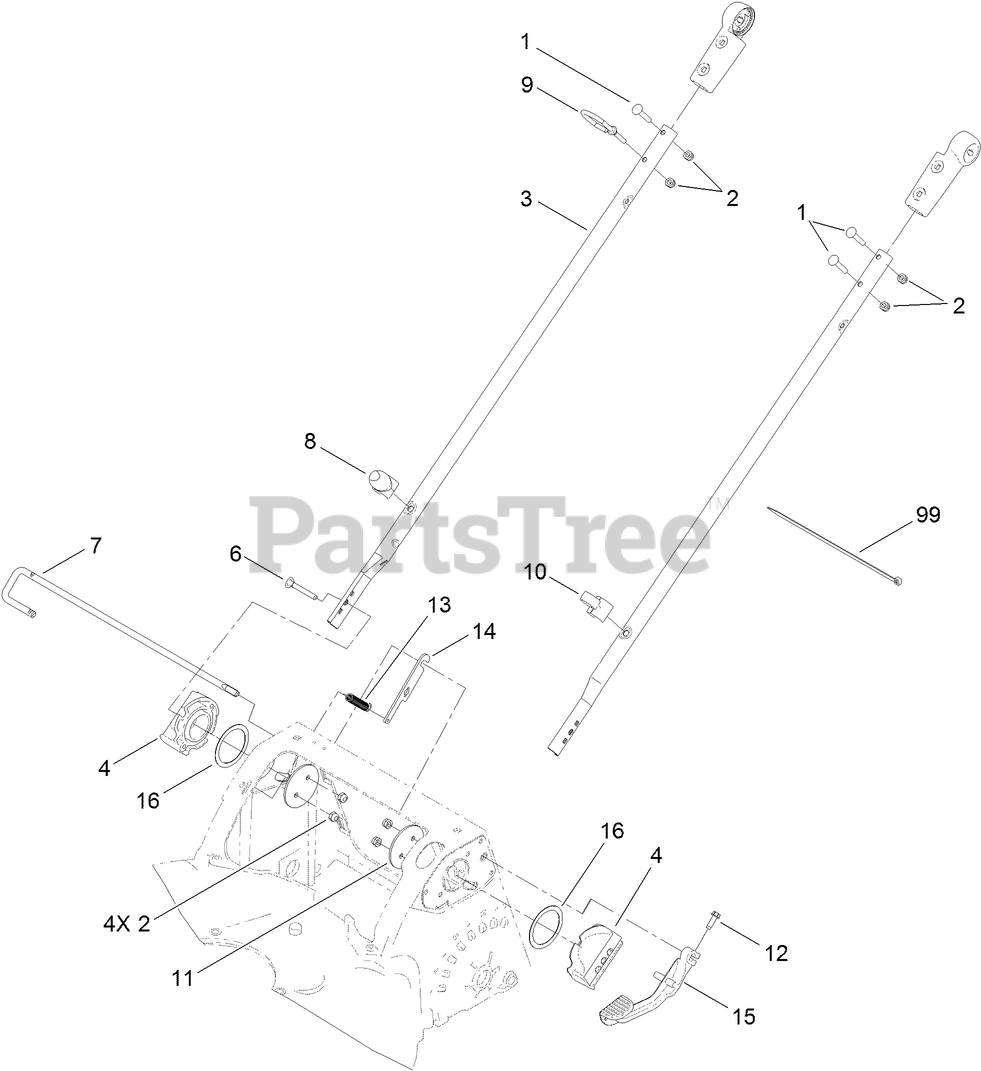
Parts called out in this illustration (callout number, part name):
1	SCREW-CARR
2	NUT-LOCK, NI
3	TUBE-LOWER
4	MOUNT-HANDLE
6	SCREW
7	ROD-RELEASE, HANDLE
8	GUIDE-ROPE, LOWER
9	GUIDE-ROPE, UPPER
10	GUIDE-CABLE
12	SCREW-HWHTF
13	SPRING-EXTENSION
14	PLATE-ROD, RELEASE
15	LEVER-RELEASE
16	WASHER-NYLON
99	TIE-CABLE
